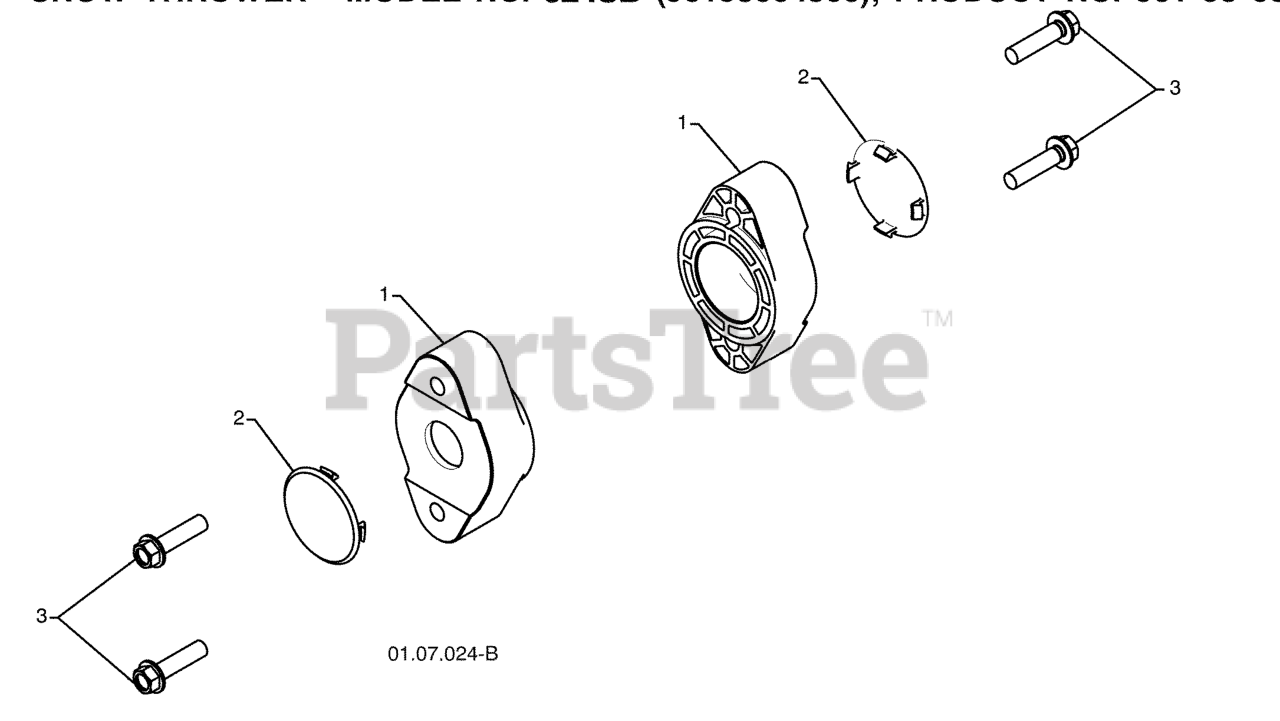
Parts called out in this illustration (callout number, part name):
1	BEARING.AUGER.SHAFT
2	PLUG.BEARING.HOLE.HSG
3	SCREW, HEX HD 5/16X1
